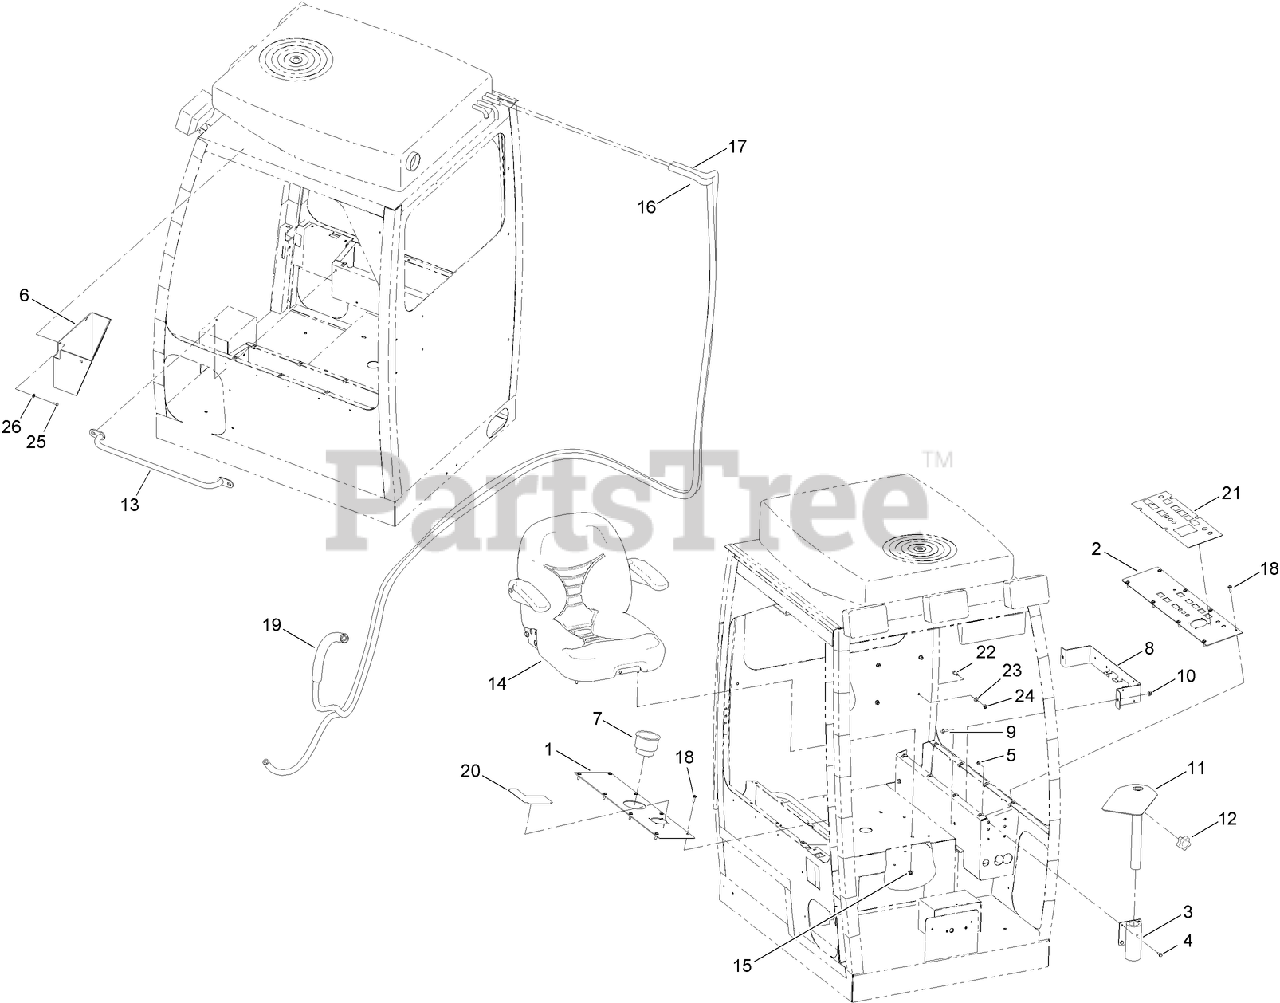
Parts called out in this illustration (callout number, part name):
1	PLATE-CONSOLE, RH
2	PLATE-CONSOLE, LH
3	MOUNT-DISPLAY
4	SCREW-HHF
5	NUT-FLANGE, NI
6	HOUSING-DISPLAY
7	CUP-HOLDER
8	PLATE-MOUNTING, ELECTRICAL
9	SCREW-HHF
10	NUT-LOCK, HHF
11	MOUNT-LOCATOR
12	KNOB-ADJUSTMENT
13	HANDLE-CAB
14	OPERATOR SEAT ASM (STATIC)
15	NUT-HF, NI
16	HOSE-HEATER
17	HOSE-HEATER
18	SCREW-PPH
19	SLEEVE-THERMAL
20	DECAL-JOYSTICK, RIGHT
21	DECAL-JOYSTICK, LEFT
22	SCREW-HH
23	WASHER-PLAIN
24	NUT-LOCK, NI
25	SCREW-HH
26	WASHER-FLAT
